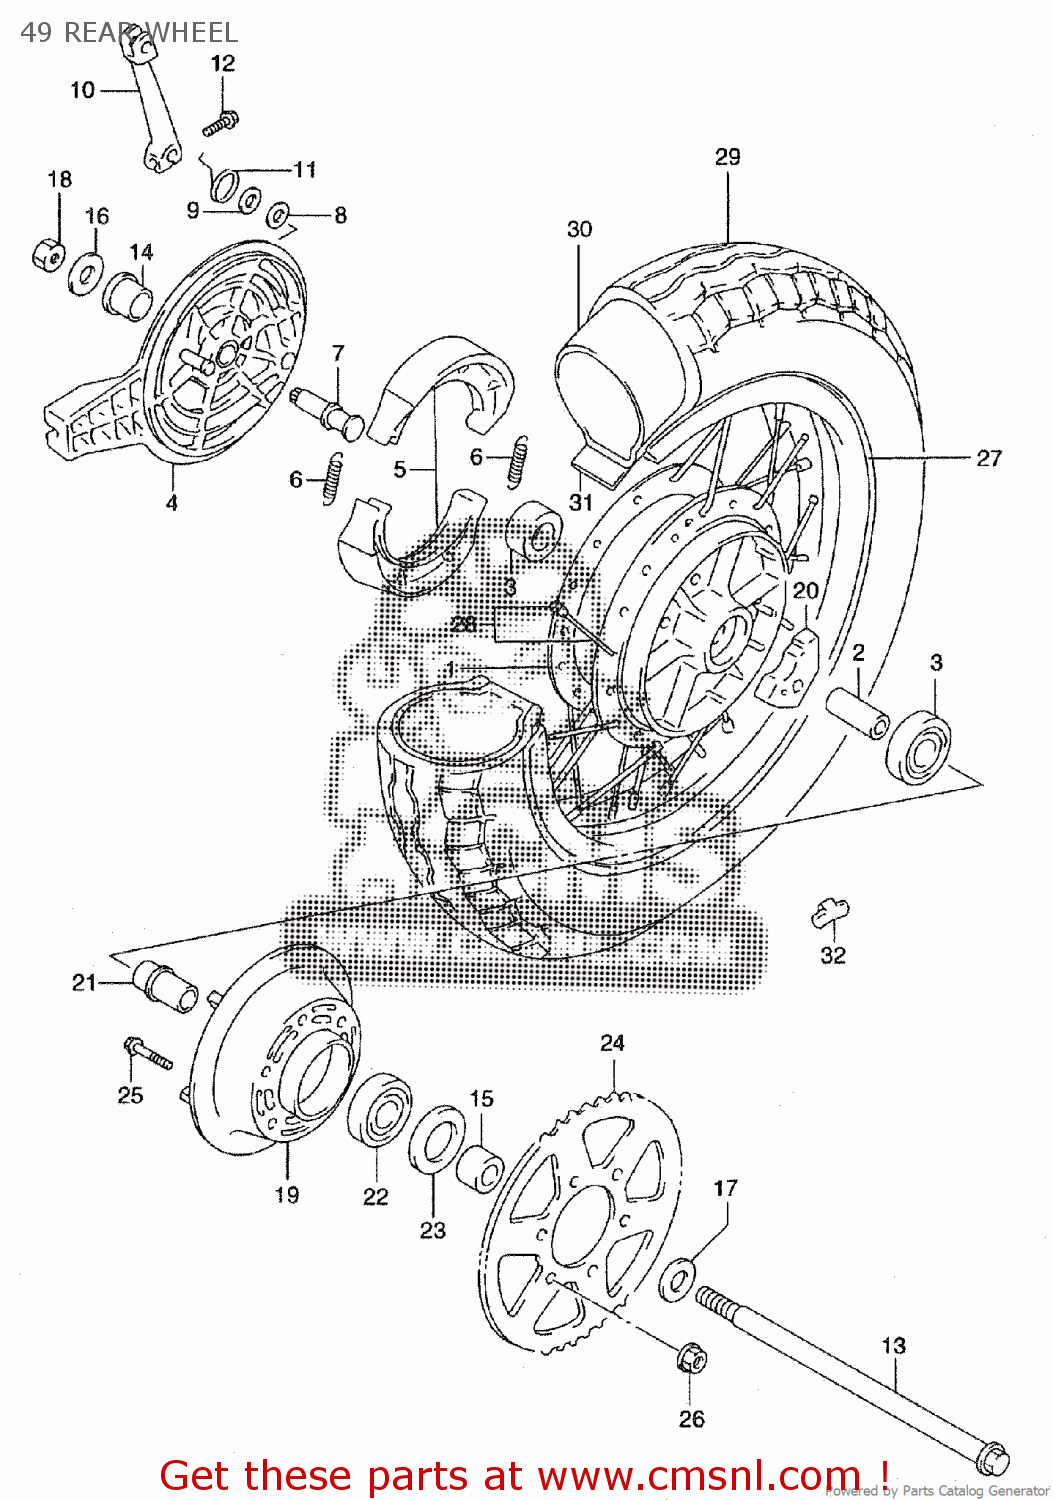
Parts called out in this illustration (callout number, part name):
1	HUB,RR WHEEL
2	SPACER(17.5X25X70)
3	BEARING
5	SHOE SET,RR BRAKE
6	SPRING,BRAKE SHOE
7	CAM,BRAKE
8	O RING(D:2.4,ID:14.8)
9	WASHER(15.5X24X1.6)
12	BOLT
15	SPACER(17X33X22.4)
16	WASHER(17X34X3)
17	WASHER
18	NUT 16MM
19	DRUM,RR SPROCKET MOUNTING
20	ABSORBER,RR HUB SHOCK
21	RETAINER,RR SPROCKET DRUM
22	BEARING(25X62X17)
23	SEAL,OIL(33X62X7)
25	BOLT(10X37.5)
26	NUT
30	TUBE ASSY,WHEEL INNER
32	BALANCER,WHEEL
